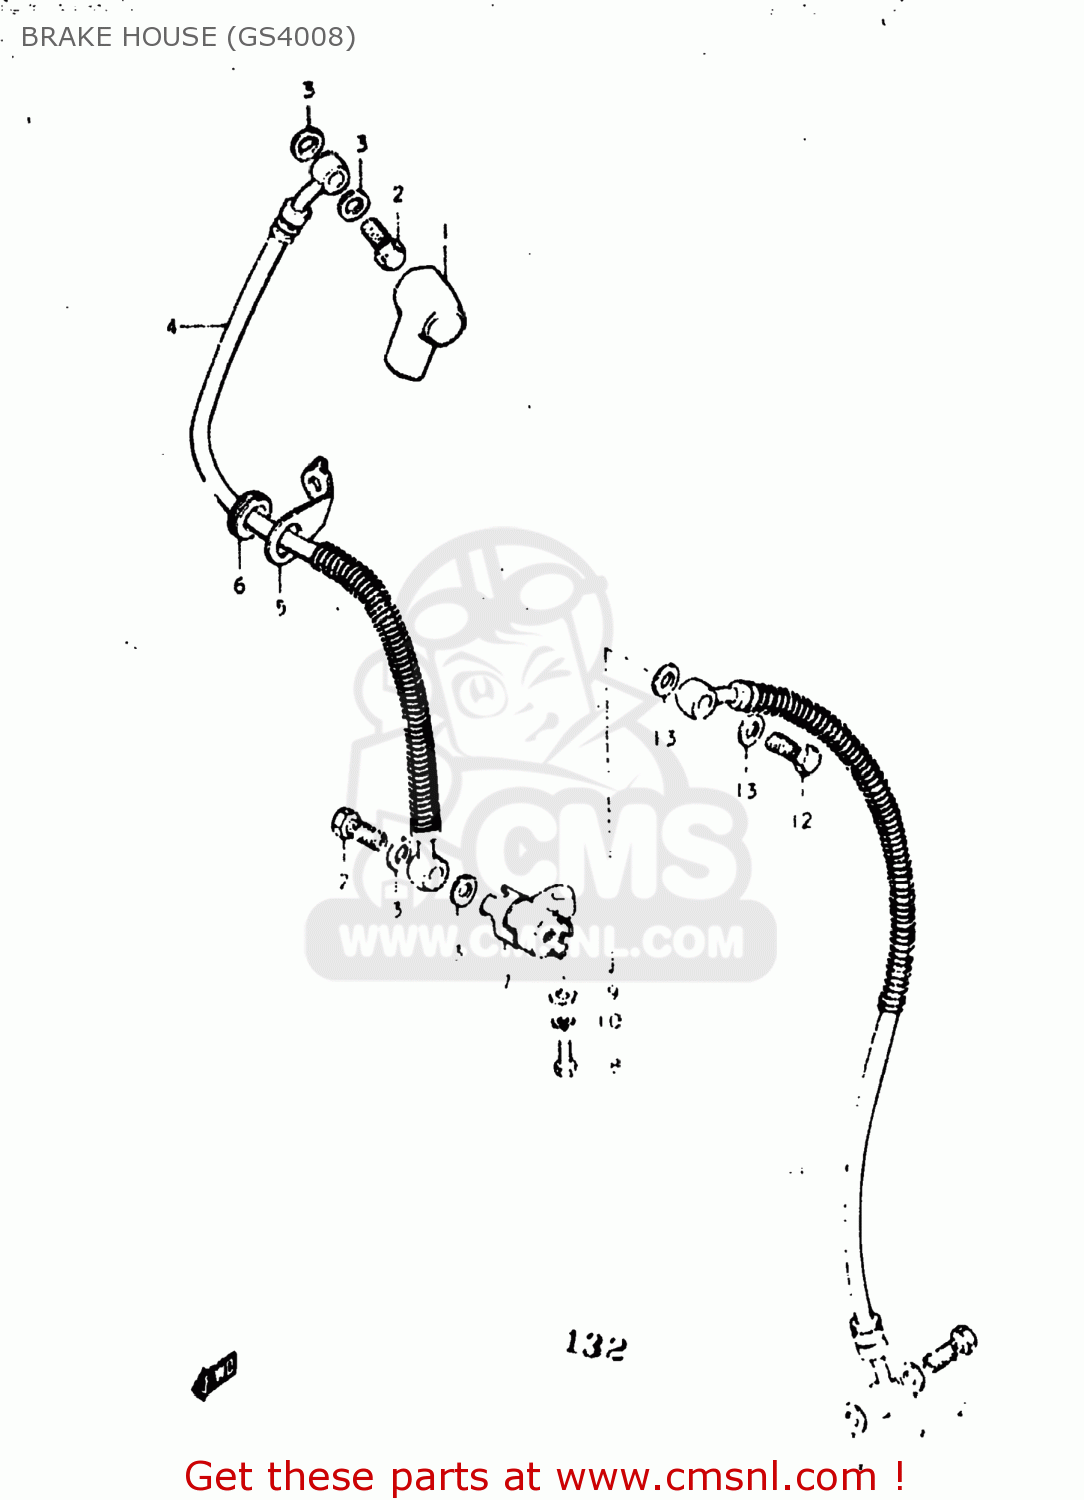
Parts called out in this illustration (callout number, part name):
1	BOOT,MASTER CYLINDER
2	BOLT UNION
3	WASHER
4	HOSE,FRONT BRAKE
5	GUIDE,BRAKE HOSE
6	GROMMET
7	JOINT,BRAKE HOSE
8	BOLT
9	WASHER
10	LOCK WASHER
11	HOSE,FRONT BRAKE
12	BOLT UNION
13	WASHER
